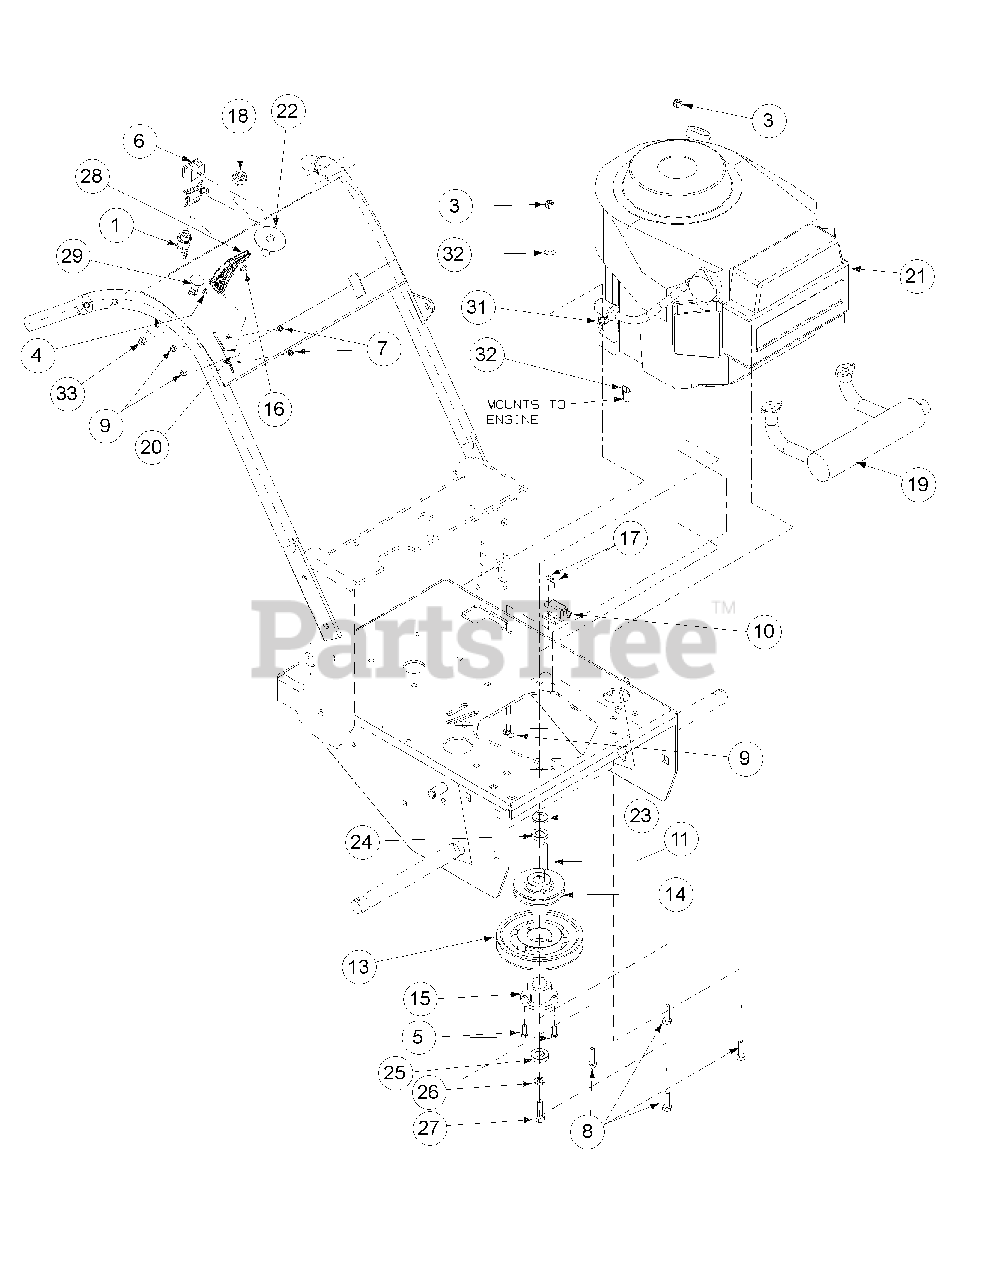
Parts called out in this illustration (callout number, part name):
1	Single Ignition ON/OFF Switch
3	Nut, 5/16-18 Nylock
4	Nut, 8-32, w/ star washer
5	Hex Cap Screw, 1/4-20, .75
6	Hour Meter includes:
7	Screw, Hex Washer, 10-32 x 1/2
8	Cap Screw, 5/16-18 x 1-3/4
9	Lock Nut, Nylon Insert, 10-32
10	Delta Switch
11	Key Stock, 1/4 x 1/4 x 2-3/4
13	Deck Pulley
14	Traction Drive Pulley
15	Bushing Type D
16	Machine Screw, 8-32
17	Machine Screw, 10-32 x 5/8
18	Nut, w/Cap, 5/8-32, Ignition
20	Throttle Control, w/Detent, 47.25
21	Engine, 15HP Kawasaki Kai
22	Decal, Pull Start Overlay
23	Engine Pulley Spacer, 12.5 Vanguard
24	Flat Washer
25	Clutch Washer
26	Lock Washer, 7/16
27	Capscrew, 7/16-20 x 1-1/4
28	Throttle Control Knob
29	Choke Cable
30	Hex Nut, 5/16-18
31	Flat Washer, 5/16 Zinc
32	Support Clamp
33	Jam Nut, 3/8-24
